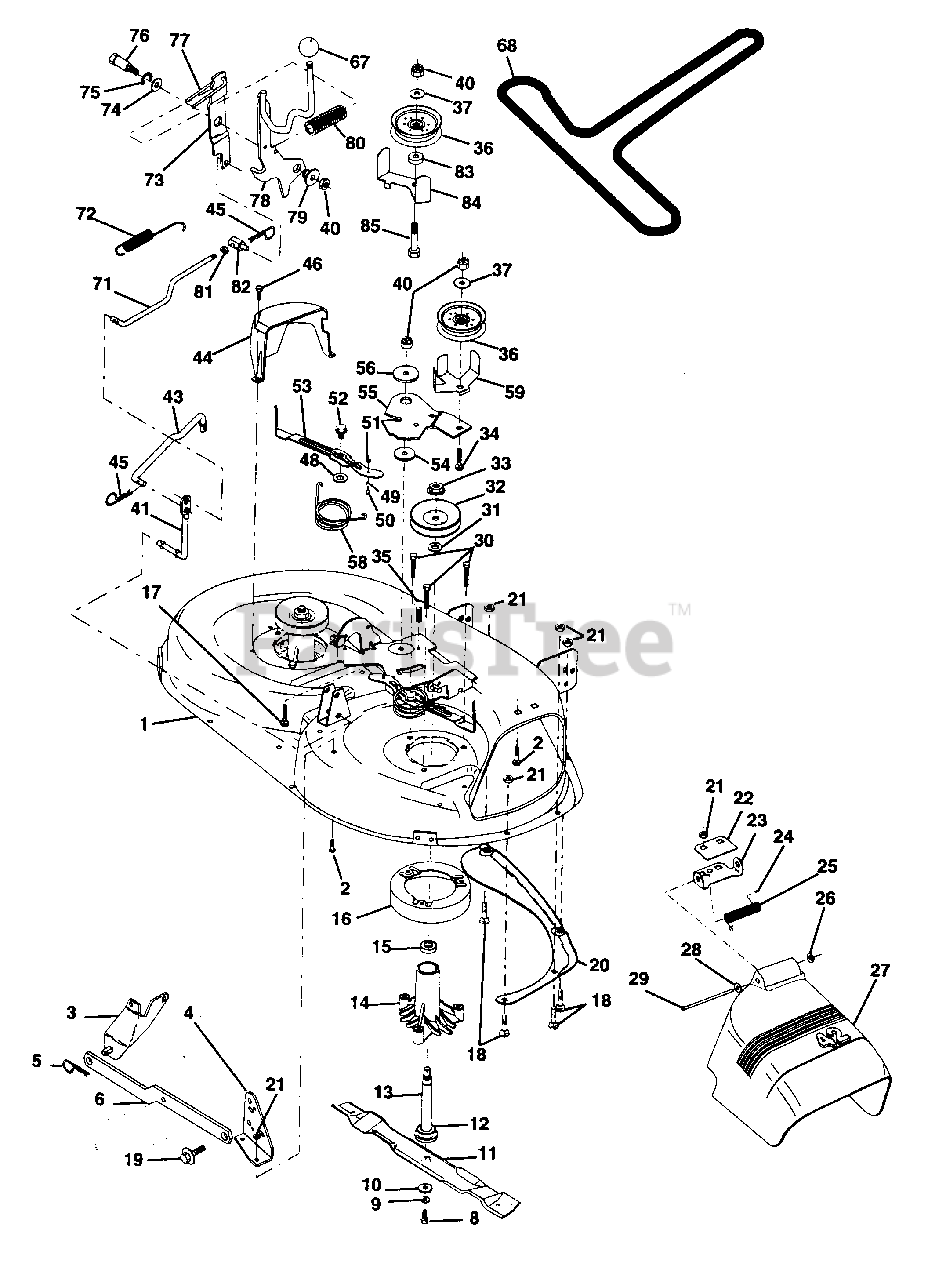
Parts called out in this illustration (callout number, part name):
1	Deck Asm MWR 42"weldment (AYP part number)
2	Bolt Rdhd Sqnk 5/16-18unc X3/4
3	Bracket Asm Fr Sway Bar 38/42 (AYP part number)
4	Bracket Asm Deck 42"sway Bar (AYP part number)
5	Retainer Spring (AYP part number)
6	Arm Suspension Rear (AYP part number)
8	Bolt 3/8 - 24 X 1.25 Gr 8 (AYP part number)
9	Washer Lock Hvy 3/8 (AYP part number)
10	Washer Hard Blade Mower Vented (AYP part number)
11	Blade Mower Mulching 42"
12	Bearing Ball #6024 (Mandrel) (AYP part number)
13	Shaft Asm W/lower Bearing
14	Housing Mandrel Vented
15	Bearing Ball Mandrel (AYP part number)
16	Stripper Mower Vented (AYP part number)
17	Bolt Rdhd Sqnk 3/8-16 X 1-1/4
18	Bolt Rdhd Sqnk 5/16-18 X 5/8 (AYP part number)
19	Bolt Shoulder (AYP part number)
20	Baffle Vortex 42 (AYP part number)
21	Nut Crownlock 5/16-18 UNC
22	Stiffener Bracket 42"deck (AYP part number)
23	Bracket Deflector Mower 42" (AYP part number)
24	Cap Sleeve 80x 112 Blk Mower (AYP part number)
25	Spring Torsion Deflector 2 52 (AYP part number)
26	Nut Push Phos & Oil (AYP part number)
27	Shield Deflector Mower 42" Blk (AYP part number)
28	Washer 11/32 X 5/8 X 16 Ga (AYP part number)
29	Rod Hinge 42"6 75 Wlg (AYP part number)
30	Screw Thdrol Hex Head Zinc Mwr (AYP part number)
31	Washer Spacer Mower Vented (AYP part number)
32	Pulley Mandrel 42" (AYP part number)
33	Nut 9/16 Toplock Flng Oil Dip
34	Bolt Rdhd 3/8-16uncx1-3/4 Gr5 (AYP part number)
35	Fastner Christmas Tree (AYP part number)
36	Pulley Idler Flat 3 060 (AYP part number)
37	Washer 13/32 X 13/16 X 16 (AYP part number)
40	Nut Crownlock 3/8-16 Unc
41	Rod Pivot W/nibs (AYP part number)
43	Rod Clutch Secondary W/nibs (AYP part number)
44	Guard Mandrel LH Black (AYP part number)
45	Spring Retainer 1" Zinc/cad (AYP part number)
46	Screw Hex Thd Cut 1/4-20x5/8 T (AYP part number)
48	Washer Hardened Smaller (AYP part number)
49	Roller Asm Cam Follower 42"dec (AYP part number)
50	Bolt Shldr 10-24 Zinc Gr 5 42" (AYP part number)
51	Nut Lock #10-24 Unc (AYP part number)
52	Bolt Shoulder 5/16-18 Unc Blkz (AYP part number)
53	Arm Asm Pad Brake (AYP part number)
54	Washer Hardened (AYP part number)
55	Arm Idler 42"mower LT/YT (AYP part number)
56	Spacer Retainer Pm Mower (AYP part number)
58	Spring Torsion Brakes (AYP part number)
59	Guard TUV Idler (AYP part number)
67	Knob Rd 1/2-13 Plstc Thds Blk (AYP part number)
68	V-Belt Mower 42"
71	Rod Clutch Primary 38/42 (AYP part number)
72	Spring Return (AYP part number)
73	Arm Clutch Secondary (AYP part number)
74	Washer 25/32 X 1-5/8 X 16 Ga (AYP part number)
75	Ring Klip #t5304-75 (AYP part number)
76	Bolt Shoulder 3/8-16 Unc 1 44 (AYP part number)
77	Keeper Spring 4 000 (AYP part number)
78	Arm Asm Clutch Primary (AYP part number)
79	Bushing 747 Od X 794 Lg Brass (AYP part number)
80	Spring Clutch Mower 2 750 Zinc (AYP part number)
81	Nut Hex Jam 3/8-16 (AYP part number)
82	Trunnion Adj 94 (AYP part number)
83	Washer Sintered (AYP part number)
84	Keeper Belt Idler Fixed (AYP part number)
85	Bolt Rdhd Sqnk 3/8-16 x 2-1/2 Gr.5 (AYP part number)
